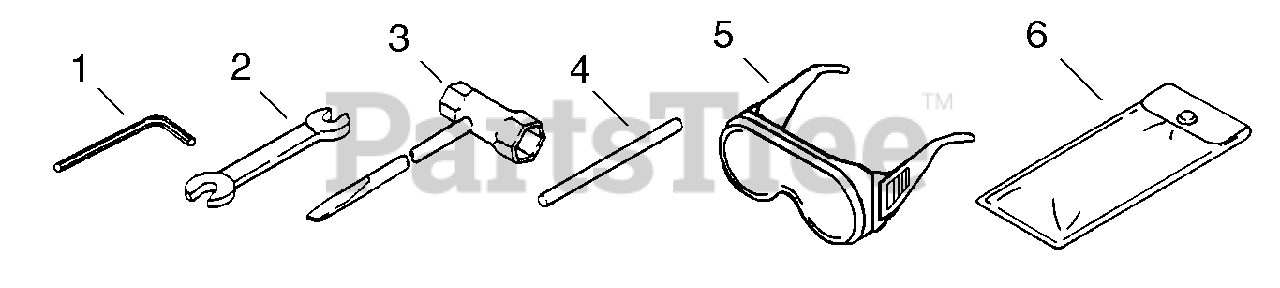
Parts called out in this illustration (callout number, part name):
1	HEX KEY - 4mm
2	SPANNER - 8X10mm
3	T-WRENCH - 17X19mm
4	ROD, LOCKING - 5X120mm
5	GOGGLES
6	BAG, TOOL
